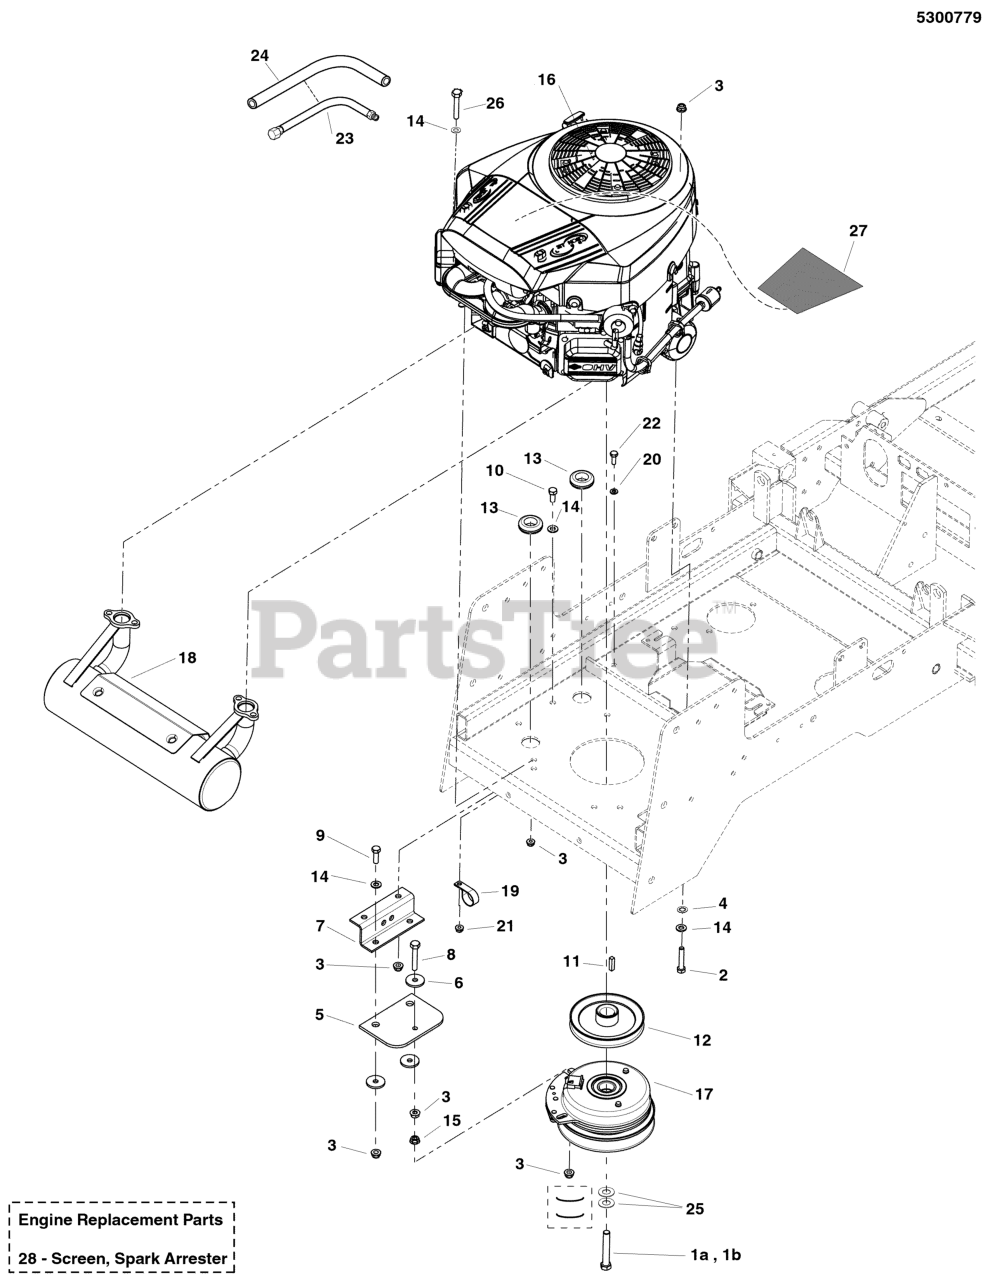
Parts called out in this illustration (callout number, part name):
2	BOLT, 5/16-18 X 1-1/2" GD5 YZ
3	NUT, 5/16-18 HEX NYLOCK FLANGE
4	WASHER, 5/16" INT. TOOTH LOCK
5	CLUTCH ANCHOR PAD
6	WASHER, .34 X 1.25 X 10 GA
7	ANCHOR, CLUTCH - BLK
8	BOLT, 5/16-18 X 2" GD5 TFL
9	BOLT, 5/16-18 X 1" GD5 YZ
10	BOLT, 5/16-18 X 3/4 GD5
11	KEY, 1/4 SQ X 1
12	PULLEY, CRANKSHAFT, 1.0005 ID X 4.95 OD
13	GROMMET, 7/8
14	WASHER, 5/16" SAE
15	NUT, 5/16-18 HEX SERRATED FLANGE (LARGE)
16	ENGINE, BRIGGS & STRATTON
17	CLUTCH, # 5219-34A
18	MUFFLER, B&S
18	MUFFLER, RIGHT OUTLET ASSY
19	CLAMP, VINYL INSULATED
20	WASHER, 1/4 SAE
21	NUT, 1/4-20 HEX NYLOCK FLANGE
22	BOLT, 1/4-20 X 3/4" GD5 YZ
23	HOSE, OIL DRAIN
24	WIRE LOOM, 1/2" ID, 11"
25	BELLEVILLE WASHER 1.1875 X .442 X .089
26	BOLT, 5/16-18 X 1-3/4" GD5 YZ
27	LABEL, POWER
